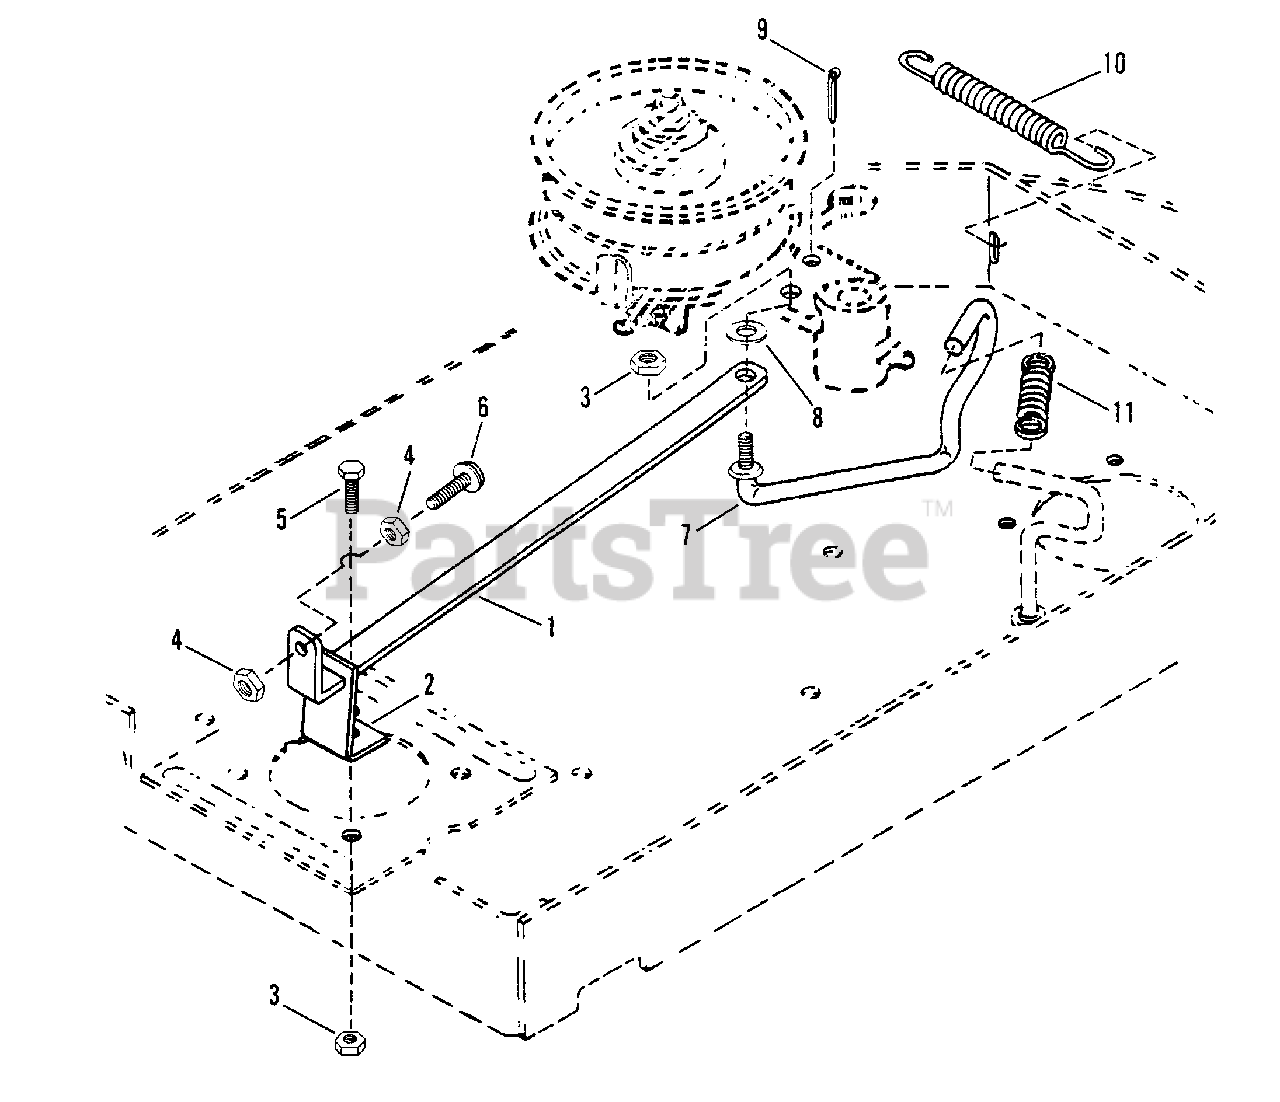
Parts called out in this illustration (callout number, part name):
1	ARM, Brake, 36" Deck
2	BRACKET, Brake Arm
3	NUT, 3/8 Nyloc
4	NUT, 5/16 Hex Jam
5	SCREW, 3/8 - 16 x 1 1/2"
6	BOLT, 5/16 - 18 x 1 1/4" Carriage
7	GUIDE, Brake Belt
8	WASHER, 3/8 Wave
9	COTTER PIN, 3/16 x 3/4"
10	SPRING, Idler Return
11	SPRING, Traction
